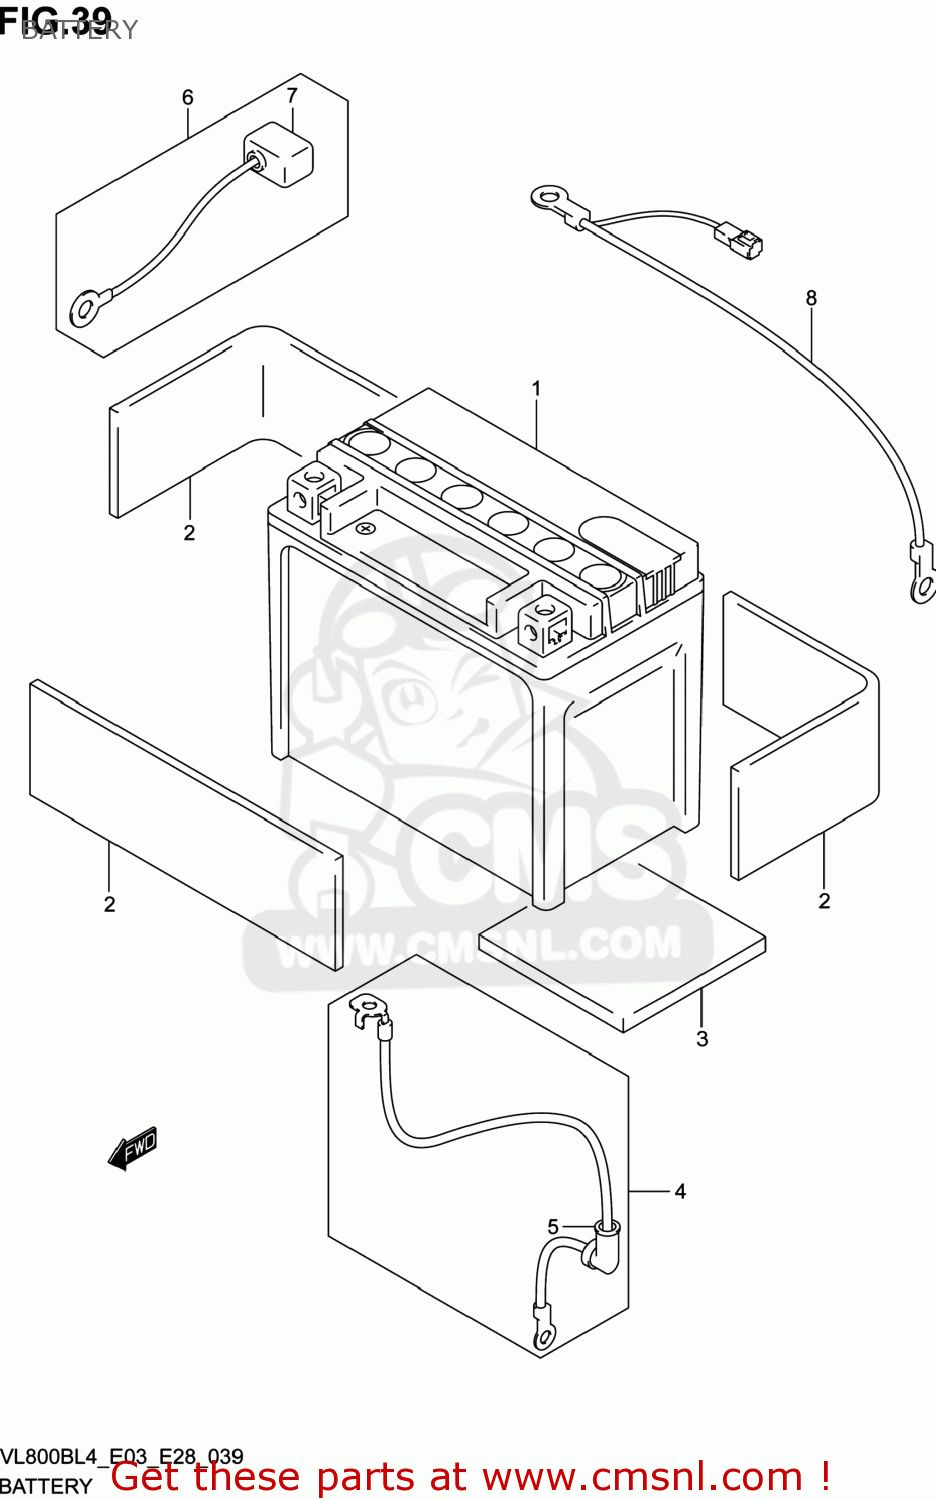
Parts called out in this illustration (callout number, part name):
1	BATTERY(FTX12-BS,12V10.5AH)
2	PROTECTOR(170X95X3.0)
3	PROTECTOR(50X50X5)
4	WIRE,STARTER MOTOR LEAD
5	CAP,STARTER MOTOR LEAD
6	WIRE,BATTERY PLUS LEAD
7	CAP,BATTERY PLUS
8	WIRE,BATTERY MINUS
